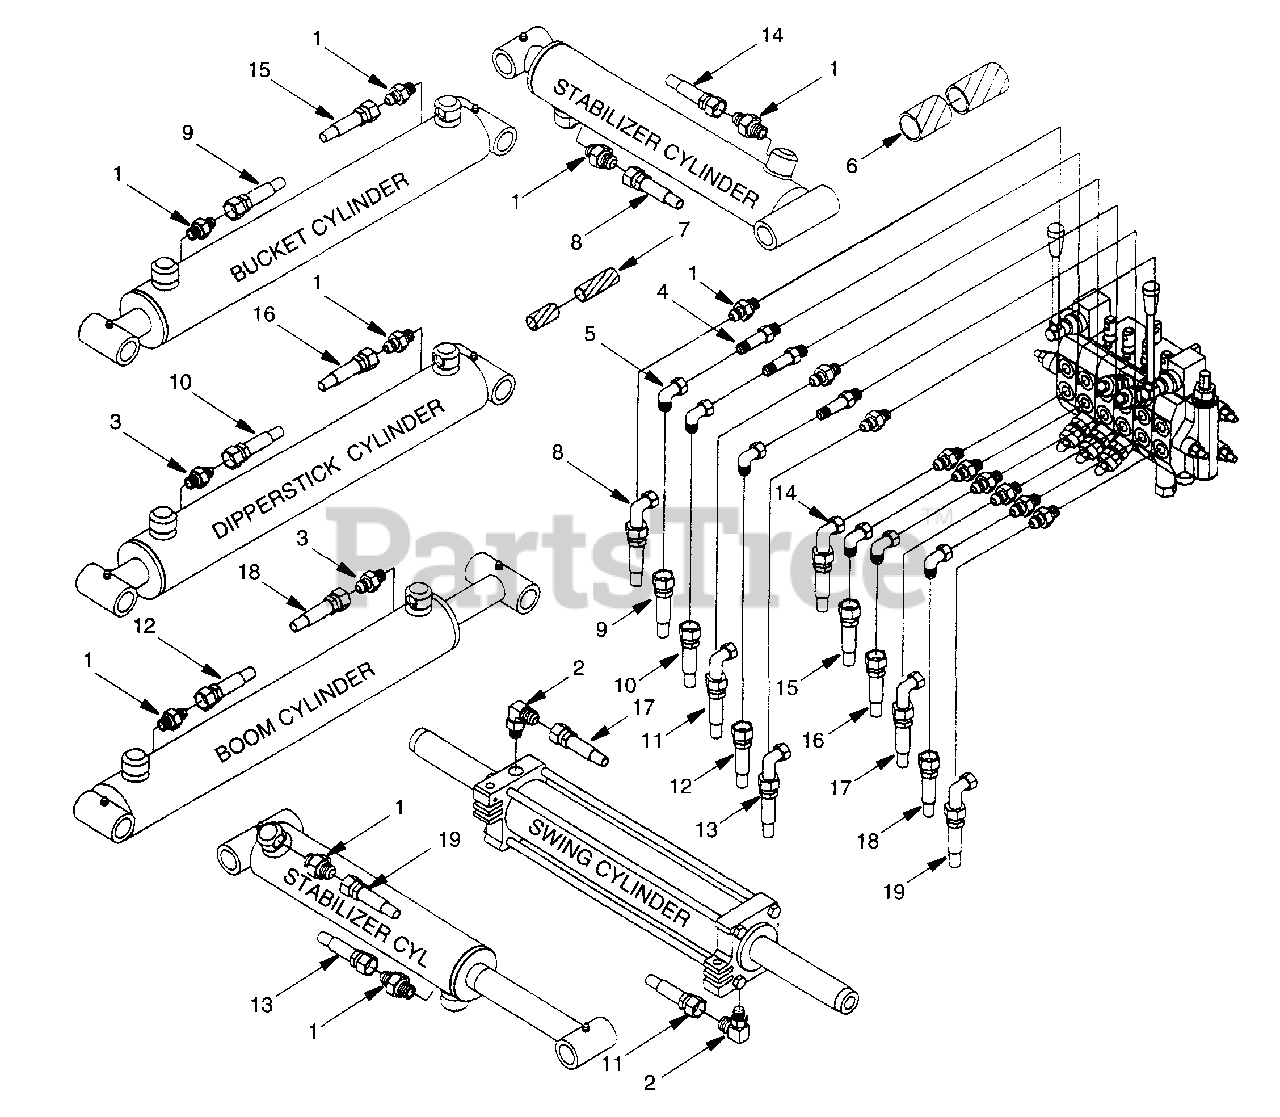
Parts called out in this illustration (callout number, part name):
1	O-Ring Connector, 9/16 - 18
2	Swivel Elbow, 9/16 x 9/16
3	Adapter w/ 3/32 Restrictor, 9/16 x 9/16
4	Straight Adapter, 9/16 - 18 x 1.9
5	Elbow, 9/16-18 Swivel x 9/16-18 Tube
6	Sleeve, 4 Dia x 34
7	Sleeve, 1 Dia x 15
8	Hose, 1/4 x 9/16 JICF x 9/16 JICF x 45
9	Hose, 1/4 x 9/16 JICF x 9/16 JICF x 94
10	Hose, 1/4 x 9/16 JICF x 9/16 JICF x 72
11	Hose, 1/4 x 9/16 JICF x 9/16 JICF x 45
12	Hose, 1/4 x 9/16 JICF x 9/16 JICF x 57
13	Hose, 1/4 x 9/16 JICF x 9/16 JICF x 45
14	Hose, 1/4 x 9/16 JICF x 9/16 JICF x 45
15	Hose, 1/4 x 9/16 JICF x 9/16 JICF x 94
16	Hose, 1/4 x 9/16 JICF x 9/16 JICF x 72
17	Hose, 1/4 x 9/16 JICF x 9/16 JICF x 45
18	Hose, 1/4 x 9/16 JICF x 9/16 JICF x 57
19	Hose, 1/4 x 9/16 JICF x 9/16 JICF x 45
